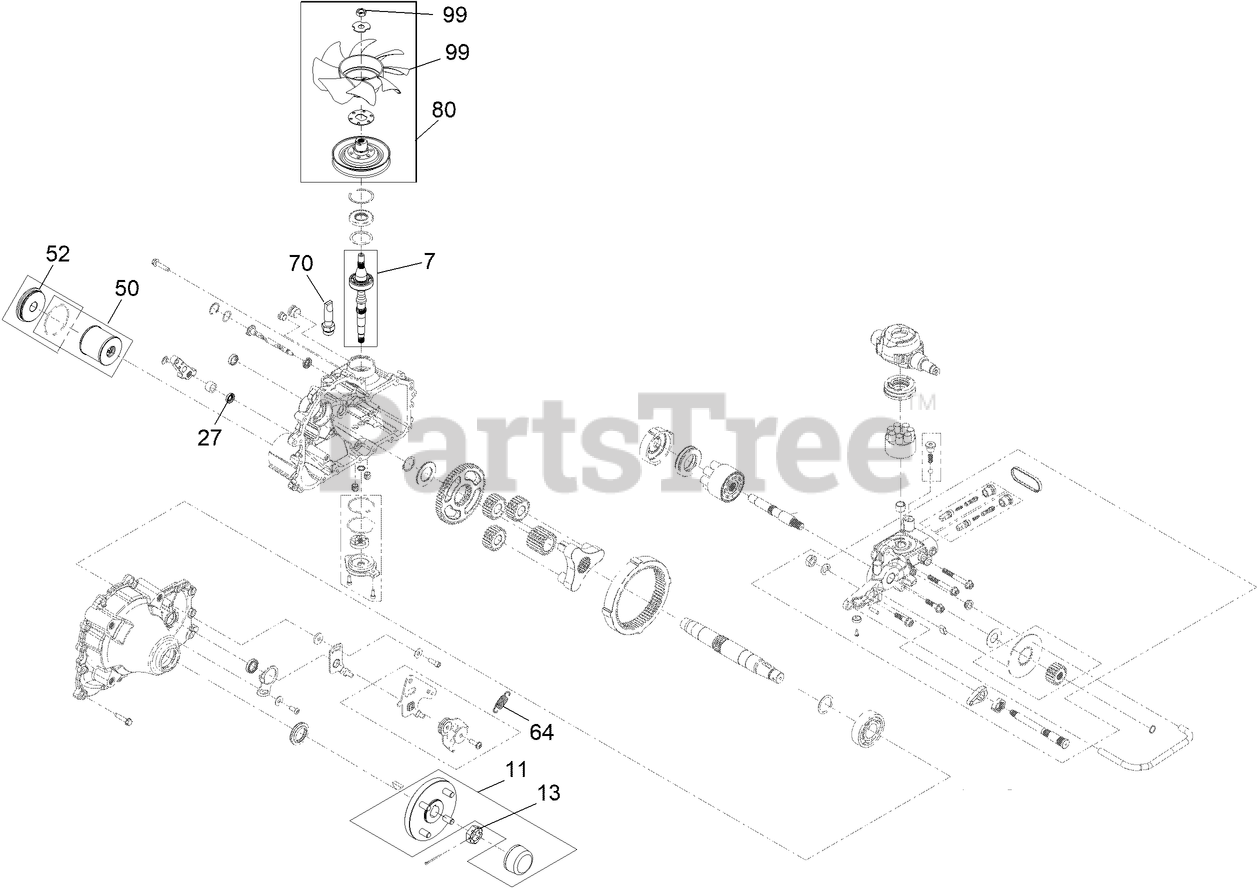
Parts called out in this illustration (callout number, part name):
7	KIT, INPUT SHAFT
11	HUB-4 BOLT
13	NUT, SLOTTED
27	SEAL, LIP-BRAKE
50	KIT, FILTER
52	KIT, FILTER PLUG
64	SPRING-EXTENSION
70	FITTING-STRAIGHT, 5/8 HOSE BARB
80	KIT, FAN AND PULLEY
99	KIT-OVERHAUL SEAL
99	FAN-8.25, 8 BLADE
